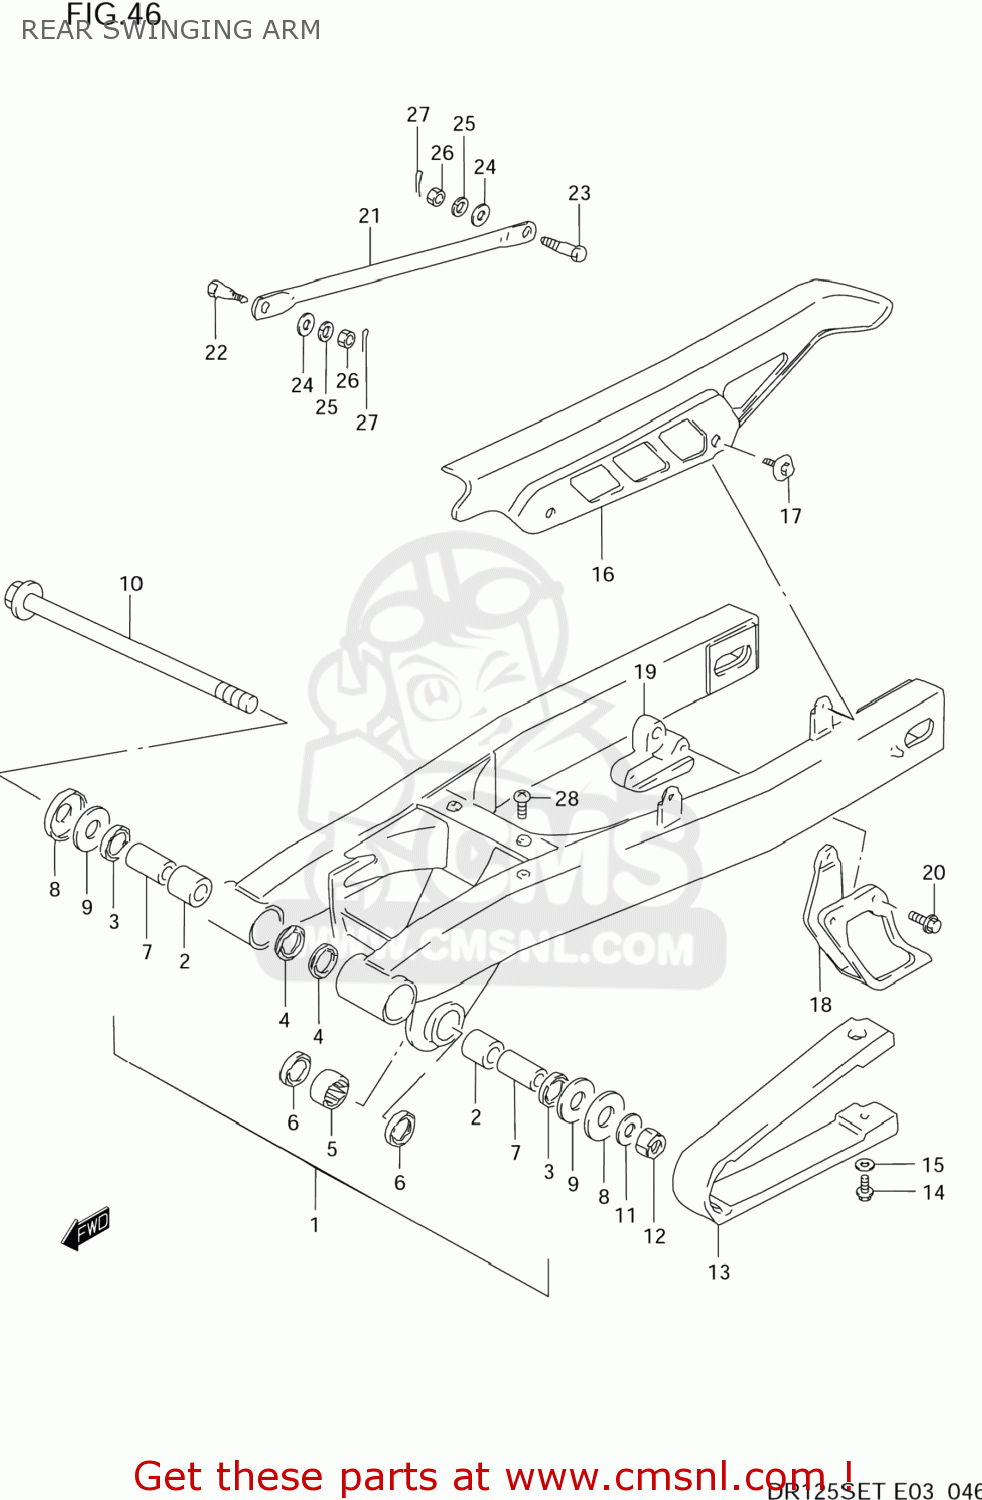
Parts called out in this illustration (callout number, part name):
1	SWINGINGARM ASSY,RR
2	BUSHING,RR SWGARM PIVOT
3	OIL SEAL
4	OIL SEAL
5	BEARING(20X27X25)
6	SEAL,CUSHION LEVER OUT DUST
7	SPACER,RR SWGARM PVT
8	COVER,RR SWGARM DUST SEAL
9	WASHER
10	SHAFT,RR SWINGINGARM PIVOT
11	WASHER
12	NUT
13	BUFFER,CHAIN TOUCH DEFENSE
14	BOLT
15	WASHER
16	CASE,CHAIN
17	BOLT(6X10)
18	GUIDE,CHAIN
19	RUBBER,CHAIN GUIDE
20	BOLT
21	TORQUE LINK,RR
22	BOLT(8X22)
23	BOLT(8X26.5)
24	WASHER
25	WASHER,LOCK
26	NUT
27	PIN 20X20
28	SCREW
